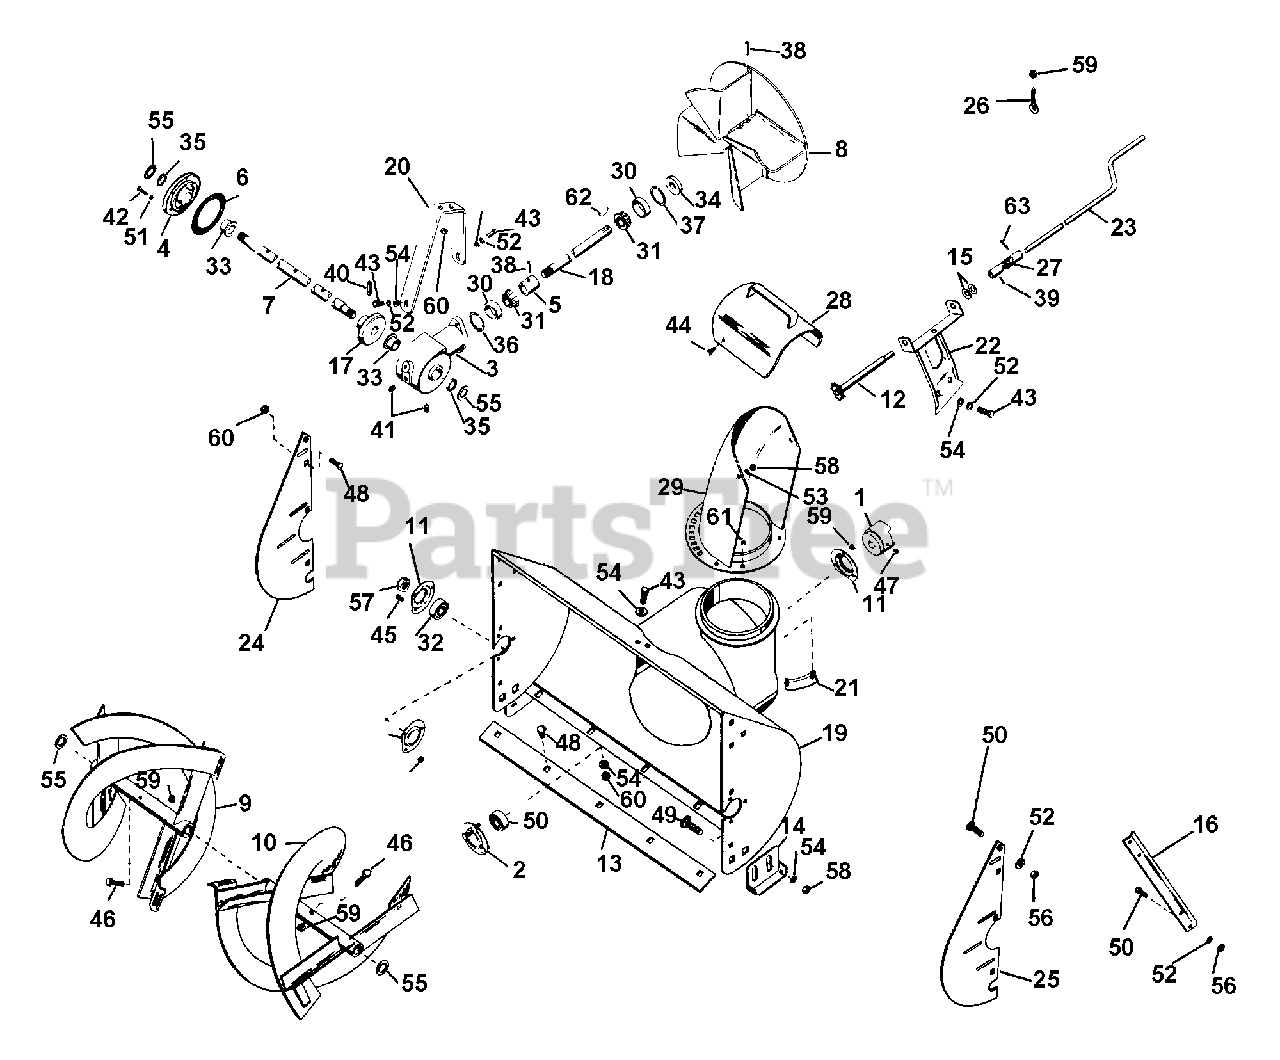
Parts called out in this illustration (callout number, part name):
1	TILLER DRIVING JAW
2	BEARING FLANGE
3	GEAR CS
4	FLNGE GEAR CS
5	BEARING SPACER
7	FRONT GEAR SHFT
9	R H RAKE
10	L H RAKE
11	BEARING FLANGE
12	CONTROL SPROCKET
13	SCRAPER BLADE 24"
14	RUNNER
15	WAVE WASHER .515 X 1.00 X .125
16	CUTTER BAR
17	HELICON GEAR
18	PINION
19	BLOW HSG
20	GEAR CS SPRT
21	CHUTE CLAMP
22	CHUTE CNTL BRACKET
23	CHUTE CNTL CRANK
24	RIGHT HAND ROTOR SHIELD
25	L H ROTOR SHIELD D
26	ROD HANGER EYEBOLT
27	UNIVERSAL JOINT
28	DEFLECTOR
29	DISCHARGE CHUTE
30	BRG-CUP 1.781X.475
31	BRG-CONE .750X.61
32	BRG-BALL .750X1.750X.50
33	BSHG-FLG .875X1.125X.625X1.500
34	SEAL .750X1.781X.250
35	SEAL .875X1.125X.125
36	RG-RTNG INT 1.781 HSG X.062
37	SNAP RING KIT
38	PIN-ROLL .250X1.25
39	PIN-ROLL .125X1.00
40	PIN-ROLL .313X1.38
41	PIPE PLUG
42	BLT-HEX .25-20X.75 PL GR2
43	BLT-HEX .31-18X.63 PL GR 2
44	BLT-HEX .31-18X.63 PL GR 2
45	BLT-HEX .31-18X.63 PL GR 2
46	BLT-HEX .44-14X1.25 PL GR2
47	SCR-SET .38-16X.50 SKHCUP OH
48	BLT-RDHDSQSHNK .31-18X.50 YZ
49	BLT-RDHDSQNK .38-16X.75 SHT PL
50	BLT-RDHDSQNK .31-18X.75 GR5 PL
51	WSHR-LK .250X.077 HVY PL
52	WSHR-LK .312X.097 PL HVY
53	WSHR-LK .375X.115 HVY PL
54	WSHR-FL-STL .38X.875X.083 PL
55	WSHR-FL-STL .531X1.062X.095 PL
56	NUT-JAM .375-16 PL
57	NUT-LK-CTR .75-16 PL
58	NUT-LK-CTR .375-16 GR A PL
59	NUT-LK-CTR .250-20 PL
60	NUT-LK .312-18 GR A PL
61	NUT-KEPS 10-24 PL
62	KEY-WDRF .188X.875X.375 SAE11
63	PIN-COTR .09X.75 PL
64	DISCHARGE CAUTION LABEL
65	DISCHARGE CAUTION LABEL
